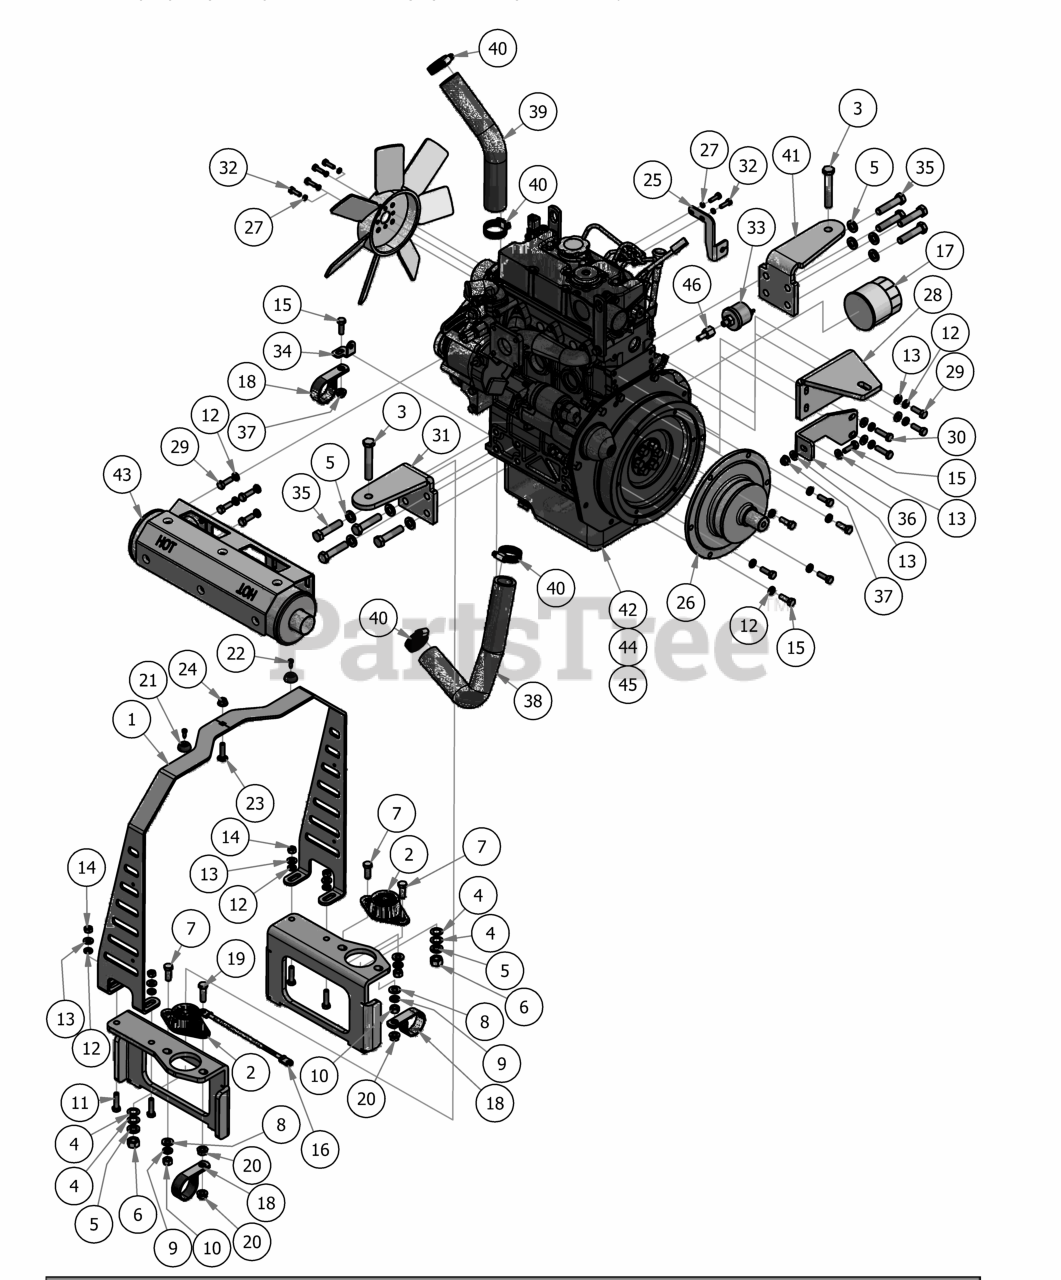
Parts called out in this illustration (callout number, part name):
1	Hood Holder Diesel
2	Rubber Isolator
3	1/2" x 3" Hex Bolt
4	1/2" Brass Washer
5	1/2" Lock Washer
6	1/2" Hex Nut
7	3/8" x 1" Hex Bolt
8	3/8" Flat Washer
9	3/8" Lock Washer
10	3/8" Hex Nut
11	5/16" x 1 1/4" Hex Bolt
12	5/16" Lock Washer
13	5/16" Flat Washer
15	5/16" x 1" Bolt
16	Black Battery Cable - Diesel
17	CAT Oil Filter
18	Diesel Clamp 1 3/4" Vinyl
19	3/8" x 1 1/2" Hex Bolt
20	3/8" Flange Nut
21	Button Bumper
22	#10 x 1/2" Self Tapping Screw
23	5/16" x 1 1/4" Carriage Bolt
24	5/16" Nylon Flange Nut
25	Diesel Throttle Bracket (4 Tier)
26	Stub Shaft
27	1/4" Lock Washer
28	Air Cleaner Support Diesel
29	M8 x 1.25 x 25mm Hex Head Bolt
30	M8 x 1.25 x 30mm Hex Head Bolt
31	Diesel Motor Side Support
32	6mm x 20mm Bolt
33	oil pressure guage sender
34	Diesel Radiator Hose Clamp Bracket
35	12mm Bolt- Diesel
36	Muffler Brace Diesel
37	5/16" Flange Nut
38	Bottom Radiator Hose for Diesel
39	Top Radiator Hose for Diesel
40	1 1/8" Hose Clamp
41	Diesel Side Motor Mount (Left)
42	1500cc CAT Diesel
43	Diesel Muffler
44	1500cc Diesel CAT (Canada Only)
45	1500cc Perkins Diesel
46	8mm x 1/8in mpt Oil Pressure Adaptor
47	Internal Fuel Filter (Not Pictured)
